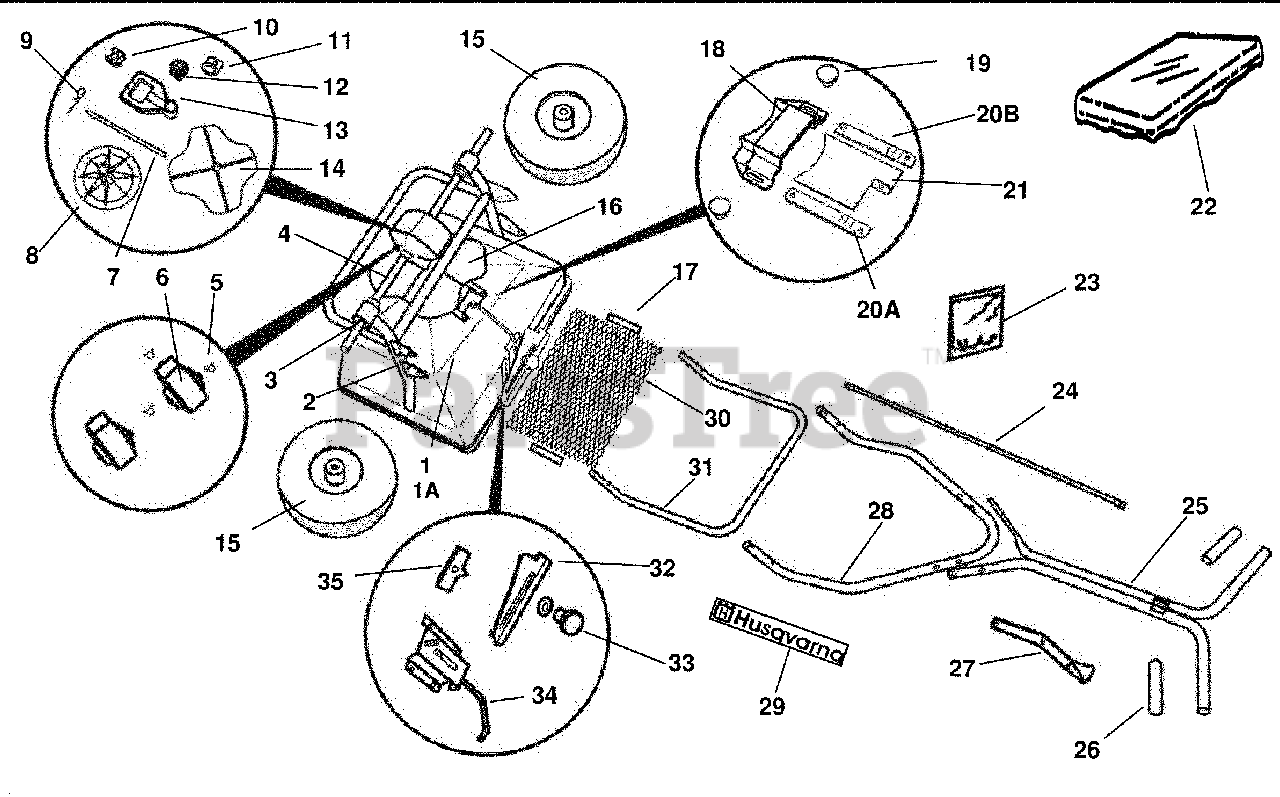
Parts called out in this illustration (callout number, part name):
1	Hopper Assembly
2	Frame Assembly
3	Axle Bearing (4 Req.)
5	Gear Cover Clamp (3 Req.)
6	Gear Cover Assembly
7	Impeller Shaft
10	Impeller Shaft Bearing
11	Axle Collar w/ Scr. (3 Req.)
12	Pinion Gear
13	Gear Support
15	Drive & Free Turning Wheel
16	Impeller Assembly
17	Screen Clip (2 Req.)
18	Discharge Chute
19	Discharge Chute Knob (2 Req.)
20A	Shutoff Plate Guide-RH.
20B	Shutoff Plate Guide-LH.
21	Shutoff Plate
22	Hopper Cover
23	Fastener Package
24	Control Tube
25	Upper Handle
26	Handle Grip (2 Req.)
27	Handle Lever Ass’y w/Chain
28	Handle Brace
29	Hopper Label
30	Hopper Screen
32	Rate Plate
33	Rate Control Knob
34	Spring Housing Assembly
